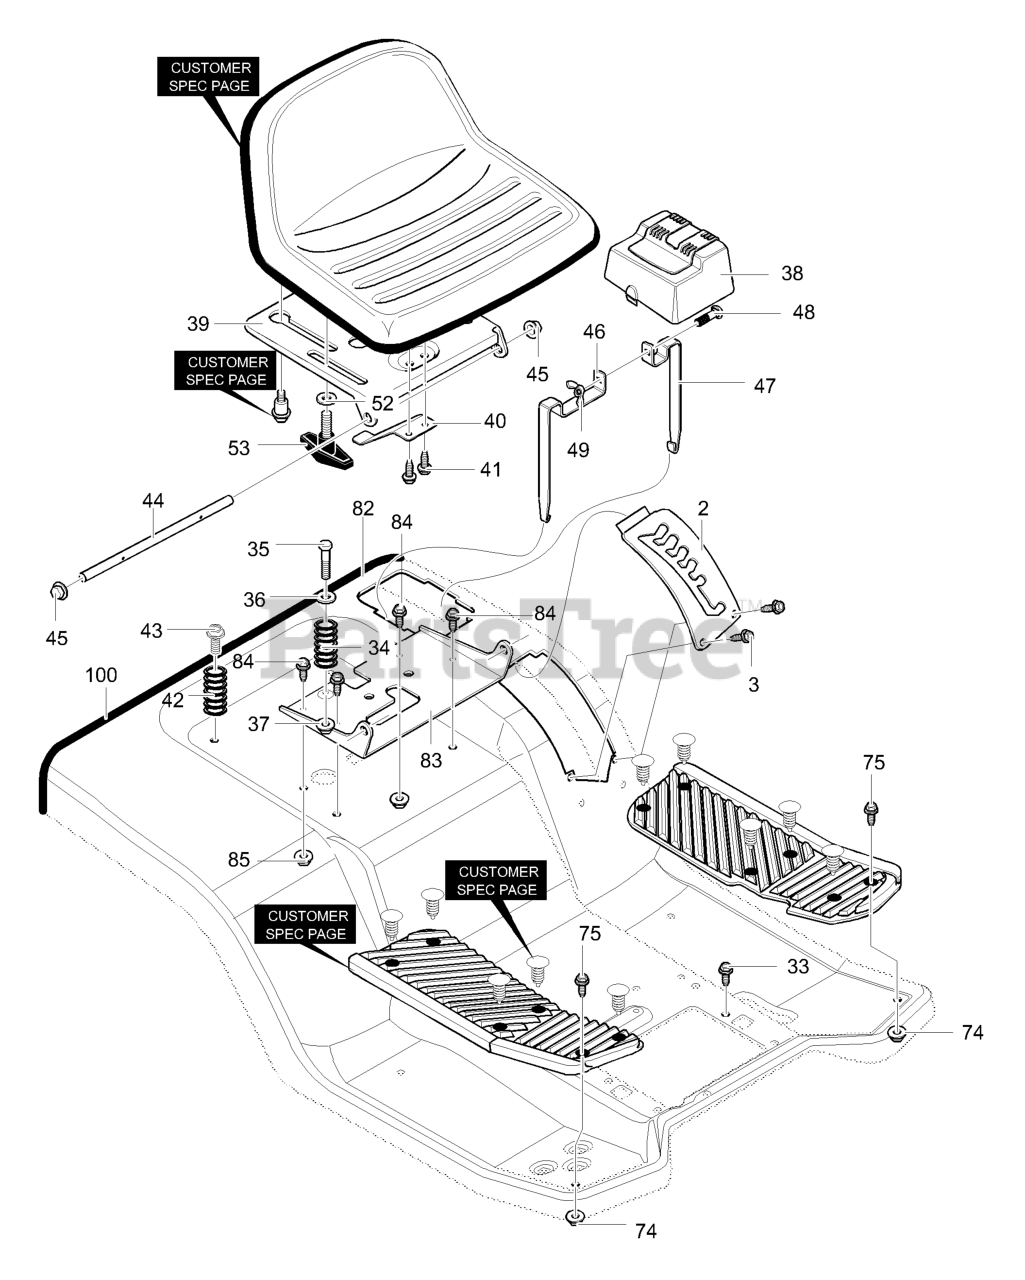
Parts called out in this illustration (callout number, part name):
2	Plate, Lift Detent
3	Screw, #12x.50
33	Screw, 5/16-18 x 0.75
34	Spring, Compression
35	Shoulder Bolt 1/4-20
36	Zinc Washer Cup
37	Nut, 1/4-20 Centerlock
38	Cover, Battery
39	Support, Seat
40	Spring - Leaf
41	Screw, 1/4-20x.50
42	Spring, Compression
43	Screw, 5/16-18 x 0.75
44	Hinge Seat Pivot
45	Nut, Push Cap
46	Battery Bracket, LH
47	Battery Bracket, RH
48	Bolt, Carriage 1/4-20x.63
49	Nut, Wing 1/4-20
52	Washer, Flat
53	Bolt, Wing 5/16-18x.50
74	Nut, 5/16-18
75	Bolt, Carriage 5/16-18x.75
82	Seat Deck Pedal
83	Bracket, Pivot Seat
84	Screw, 5/16-18 x 0.75
85	Nut, 5/16-18
100	Trim 41.00 Inches
